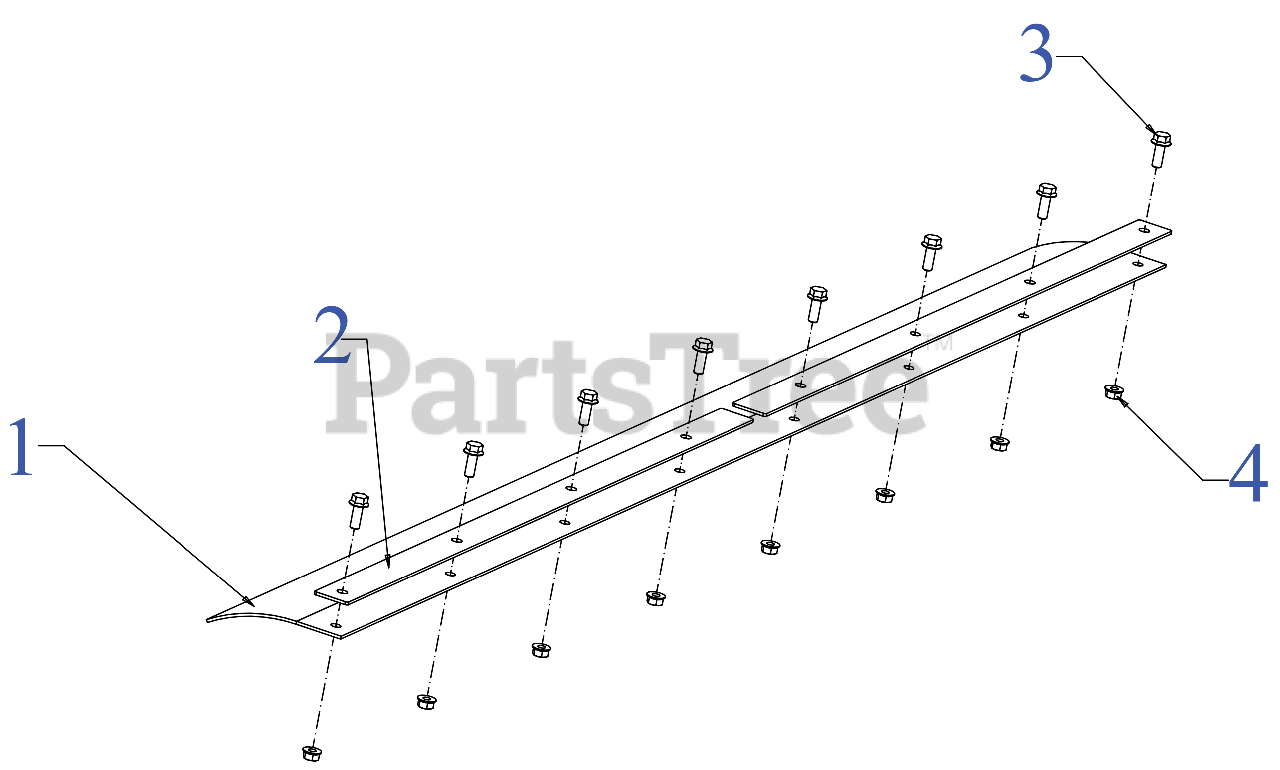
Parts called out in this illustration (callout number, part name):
1	RUBBER FLAP
2	72" HOLD DOWN BAR
3	HEX SCREW 3/8-16
4	HEX FLANGE NUT
